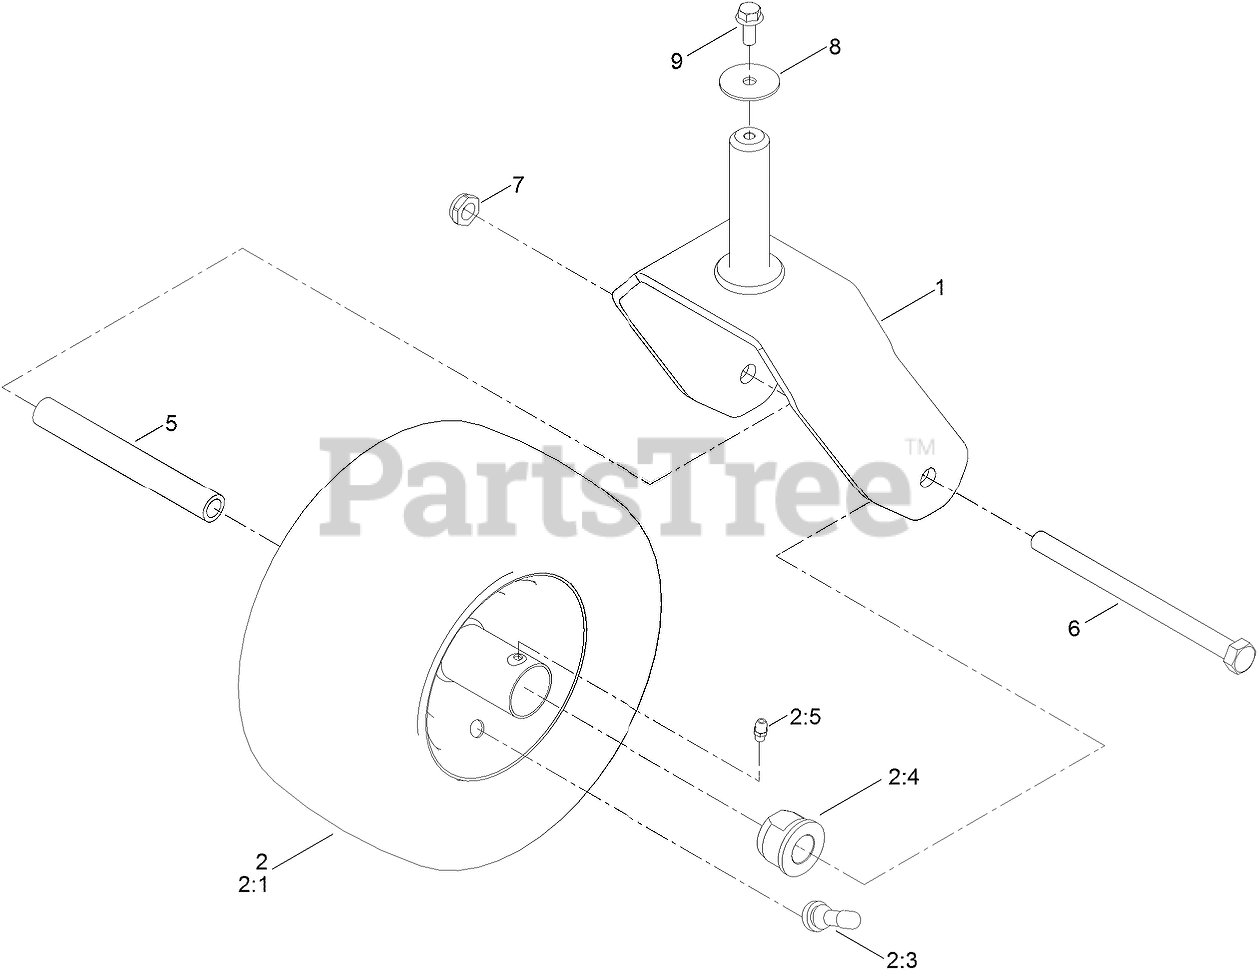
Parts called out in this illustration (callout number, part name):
1	FORK ASM
2	TIRE ASM
2:4	BUSHING-FLANGE
2:5	FITTING-GREASE
5	SPACER-SPANNER
6	SCREW-HH
7	NUT-HEX
8	WASHER-FLAT
9	SCREW-HHF
